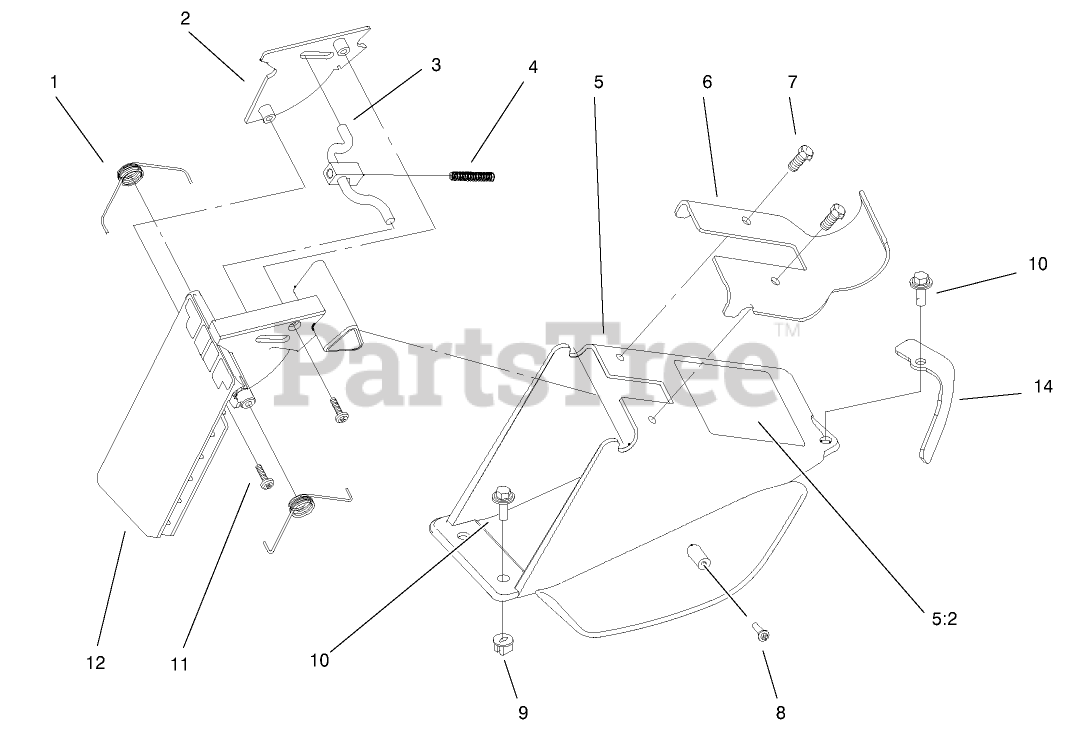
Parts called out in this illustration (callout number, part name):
1	SPRING-DOOR, RH
2	DOOR COVER
3	LATCH-DOOR
4	SPRING-COMPRESSION, LATCH
5	DISCHARGE CHUTE ASM
5:2	DECAL-DANGER
6	Plate-Discharge Chute
7	SCREW-PLASTITE
8	SCREW-PPH
9	NUT - CLIP
10	SCREW-HWH
12	DOOR-DISCHARGE
14	CLAMP-DOOR
